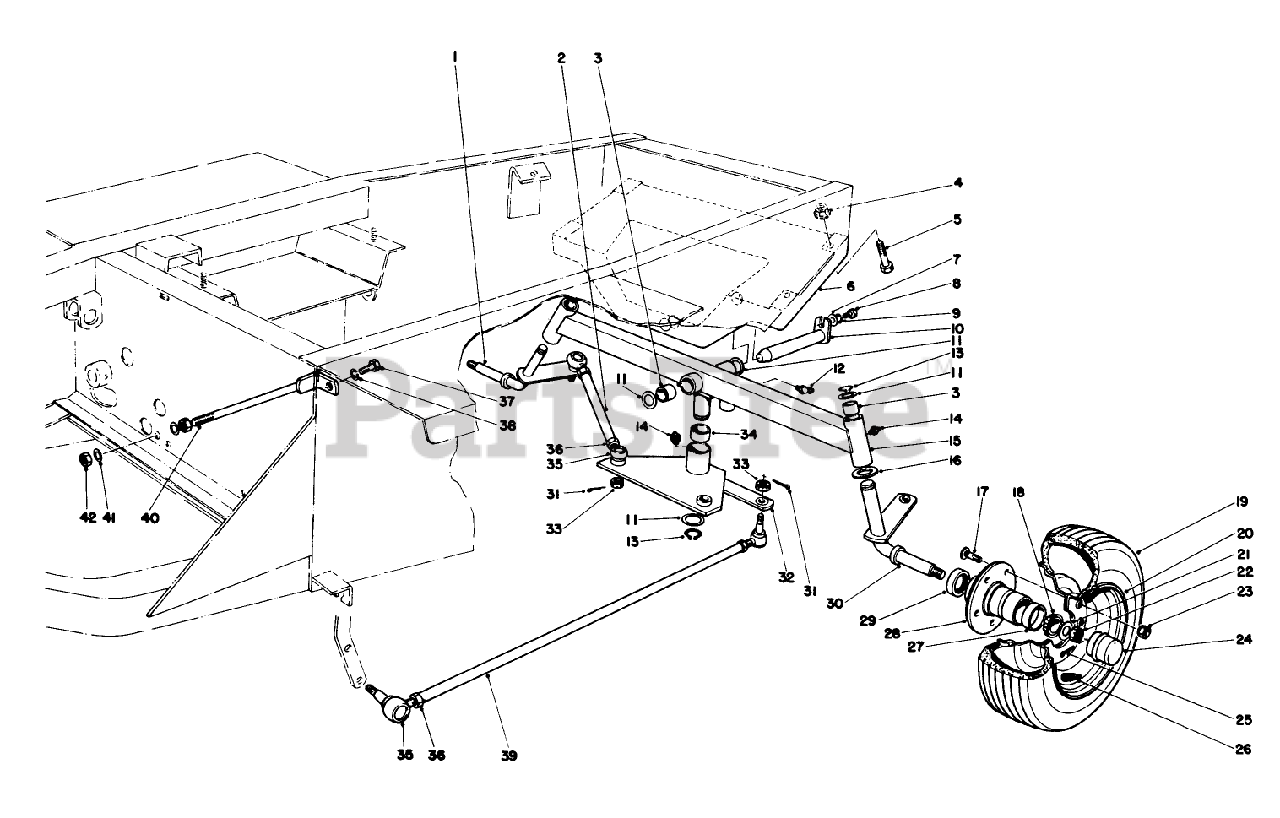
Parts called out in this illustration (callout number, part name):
1	Spindle R.H.
2	TIE ROD-STEERING
3	BUSHING
4	NUT-HF
5	SCREW-HH
6	REAR AXLE MT R
7	WASHER-PLAIN
8	SCREW-HH
9	WASHER-LOCK
10	REAR AXLE PIN WA
11	WASHER-THRUST
12	FITTING-LUBE, 45 DEG
13	RING-RETAINING
14	FITTING-GREASE
15	Rear Axle (Incl. Ref. #3)
16	WASHER-THRUST
17	STUD-TYPE, DRIVE
18	BEARING-CONE, TAPERED
19	Tire
20	WHEEL-8 INCH
21	WASHER-FLAT
22	NUT-HEX, SLOTTED
23	NUT-LUG
24	CAP-DUST
25	PIN-COTTER
26	STEM-VALVE
27	BEARING-CUP, TAPERED
28	Wheel Hub (Incl. Ref. #17 & 27)
30	Spindle L.H.
31	PIN-COTTER
32	Rear Steering Pivot (Incl. Ref. 34)
33	NUT-SLOTTED
34	BUSHING
35	Socket
36	NUT-JAM
37	SCREW-HH
38	WASHER-LOCK
39	REAR STRG TUBE PP
40	Axle Support
41	WASHER-FLAT
42	NUT-HH
